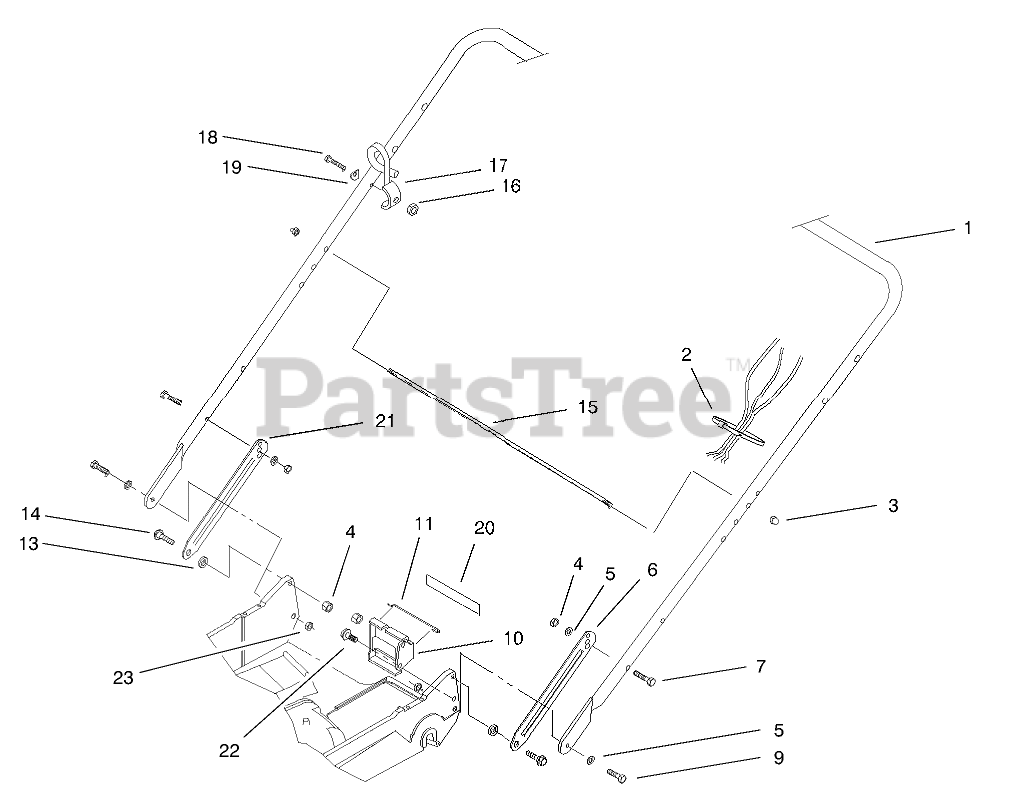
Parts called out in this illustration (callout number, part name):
1	Handle
2	TIE-CABLE
3	NUT-CAP
4	NUT-LOCK, NI
5	WASHER-BELLEVILLE
6	Latch-Handle
7	SCREW-HH
9	SCREW-HH
10	BRACKET-ADJUSTMENT, TRACTION
11	RETAINER-CABLE
13	SPACER
14	SCREW-SHOULDER
15	ROD-SUPPORT, BAG
16	NUT-LOCK, NI
17	GUIDE-ROPE
18	SCREW-HH
19	WASHER
20	DECAL-POSITION, GEAR
21	Latch-Handle
22	SCREW-HWHTF
23	NUT-LOCK, NI
